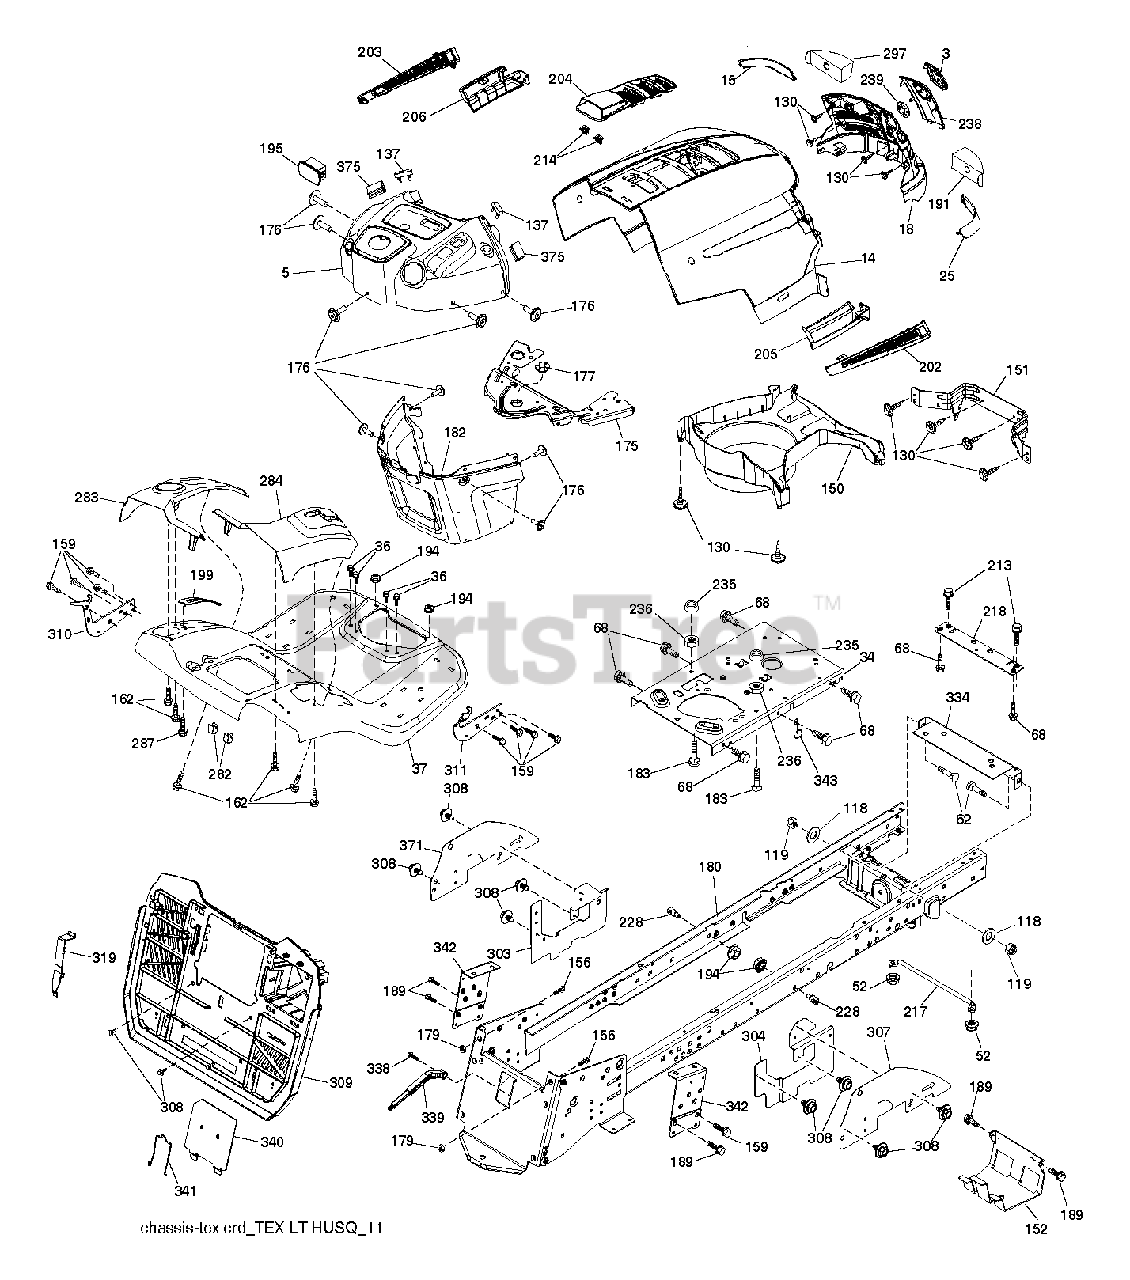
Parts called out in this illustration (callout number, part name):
3	LOGO.HUSQ.GT.LT.CROWN.H
5	DASH.UP.HUS.LT.CABLE.CLUTCH
14	HOOD.HUSQVARNA.LT.ORANGE
15	LENS.HUSQVARNA LT.RH
18	GRILLE.SVC.HUSQVARNA.GREY
25	LENS.HUSQVARNA LT.RH
34	PLATE.ENGINE.10GA.CRD.GENII
36	SCREW 5/16"
37	FENDER.TEX.SRD.CRD.FRN.GUARDS
52	LOCKNUT
62	BOLT D
68	SCREW LT
118	WASHER
130	SCREW.#10 X 0.750.BOS
137	BUMPER DASH
151	BRACKET PIVOT
152	SHIELD.BROWNING.W/TEX
159	SCREW, 3/8-16X3/4
162	SCREW.HI-LO.CONSOLE
175	CROSSMEMBER
176	SCREW.#10-24X5/8.RN.QU
177	BUSHING STEERING
180	CHASSIS WLDT TEX CRD
182	DASH.LOWER.PREDATOR LT
183	BOLT.5/16-18X1-1/4 FULL THD
189	SCREW
191	INSERT.REFLECTIVE.RH.
194	NUT LOCK HEX FLANGE 5/16-18
195	PLUG.TEX.DASH.SVC.MINDER.GREY
199	PLATE DECK LIFT
202	VENT.SIDE.HUSQVARNA.LT.RT
203	VENT.SIDE.HUSQVARNA.LT.LFT
204	SUBASM.TOP.VENT.HUSQ.LT
205	SKIRT.SIDE.HUSQVARNA.LT.RT
206	SKIRT.SIDE.HUSQVARNA.LT.LEFT
213	BOLT
214	CLIP.RETAINER.TINNER.
217	ROD.PIVOT.HOOD
218	X-PIECE.HOOD.STOP.NON/
228	STUD.FASTNER.W/ANTI-ROTATE
235	SPACER FENDER
236	NUT.CENTERLOCK.5/16-
238	TRIM.HUSQ LT.668
282	CLIP.RETAINER.CONSOLE.LT.HUSQ
283	CONSL.DECKLIFT.LH.SRD.TEX.CRD
284	CONSL.SHIFT.GEAR.RH.SRD.GREY
287	SCREW 1/4X20
297	INSERT REFLECTIVE
303	SHIELD.LWR.LH.LT.30DECK.CRDSRD
304	SHIELD.LOWER.RH.CRD.GEN.PNT
307	SHIELD.UPPER.CRD.SRD.ISO
308	BOLT, 5/16-18 X 1 3/4
309	BACKPLATE.TEX.CRD
310	LH.ADJUST.HANGER.BRACKET.ASM
311	RH.ADJUST.HANGER.BRACKET.ASM
319	BRACKET.ACTUATOR.BAGGER.SRD
334	BRACKET.ENGINE
338	BOLT BOLT SHOULDER
339	LEVER LEVER BAGGER
340	DOOR.PNT.BATTERY.TRY.TEX.CRD.
341	LATCH
342	SUPPORT SUPPORT FENDER
343	CLIP CLIP
371	SHIELD.UPPER.CRD.SRD.ISO
375	BUMPER CLIP-ON. DASH 1"
